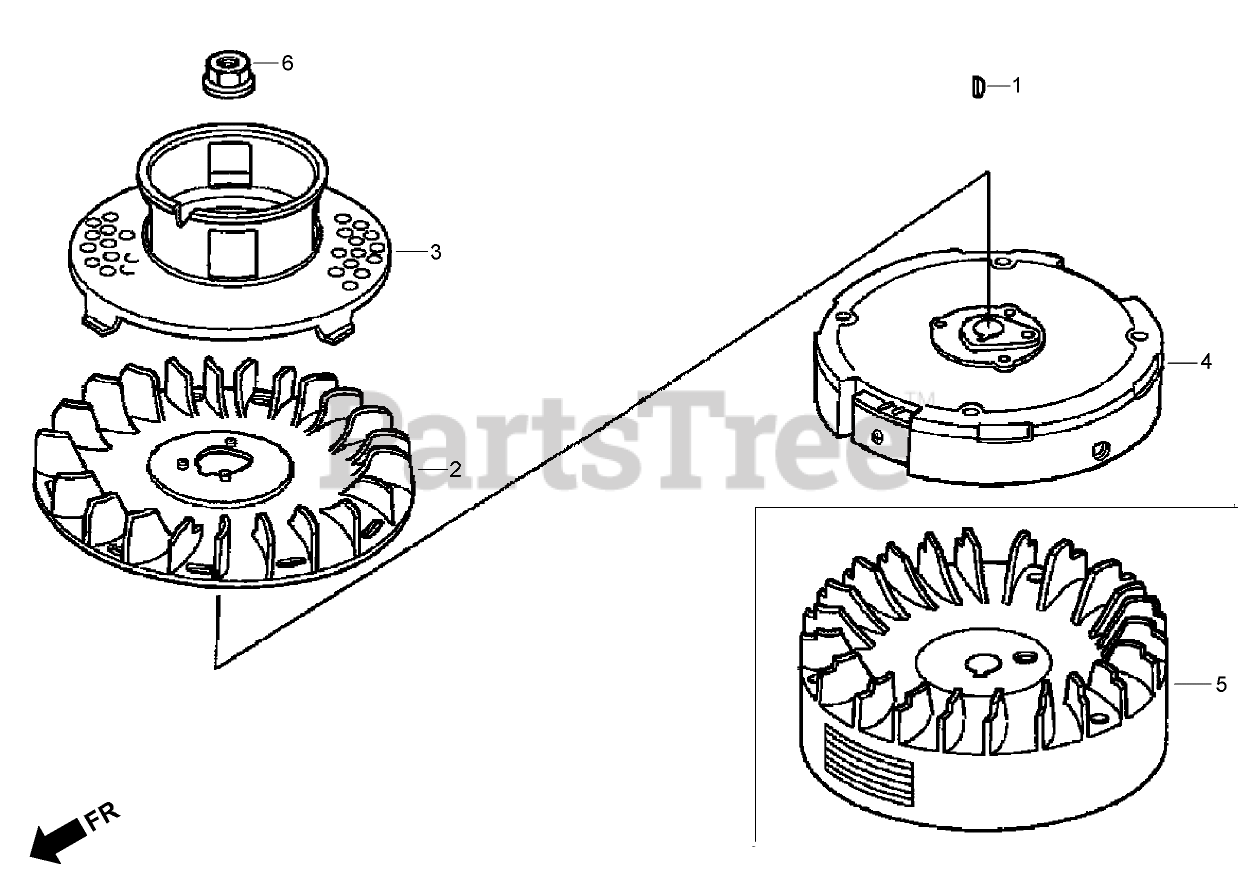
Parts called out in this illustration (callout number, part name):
1	KEY-WOODRUFF, SPECIAL (25X18)
2	FAN-COOLING (Engine Serial No. From 1036456)
3	PULLEY-STARTER
4	FLYWHEEL (Engine Serial No. From 1036456)
5	FLYWHEEL (BRAKE) (Engine Serial No. Up To 1036455)
6	NUT-SPECIAL (14 mm)
